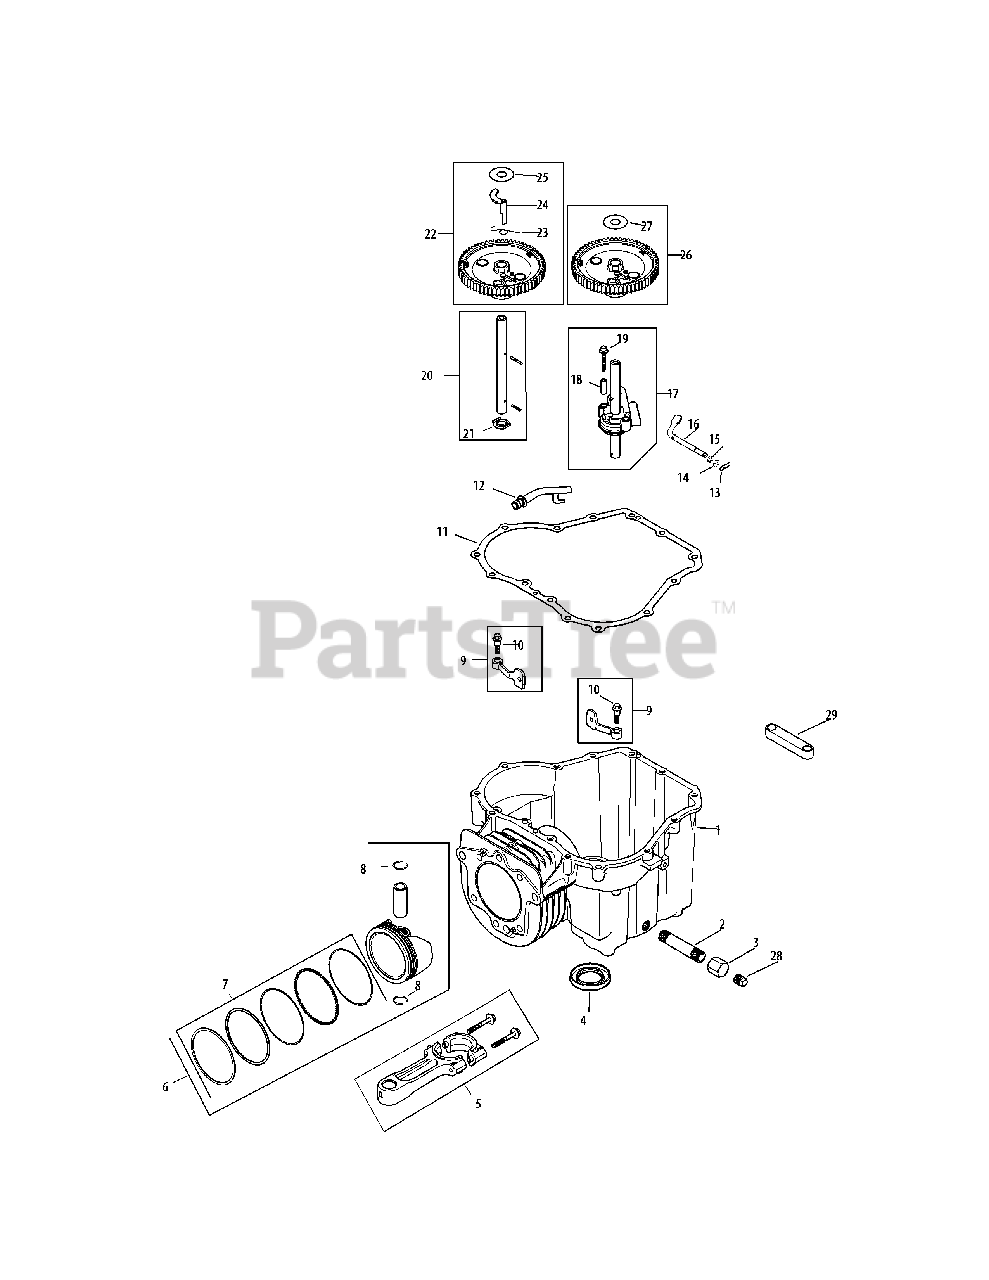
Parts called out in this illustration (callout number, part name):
1	Crankcase
4	Oil Seal
5	Connecting Assembly Rod
6	Piston w/ Ring Set, 94mm (Incl. 7, 8)
7	Ring Set (94mm)
8	Piston Pin Retainer
9	Cam Lever Ass. Kit (Incl. 10)
10	Shd. Thd. Frm. Screw, M6 X 1 X 26
11	Gasket
12	Drainback Tube
13	Hitch Pin Clip
14	Flat Washer, 6 Mm
15	Flat Washer, 1/4
16	Governor Cross Shaft
17	Oil Pump Ass’y Kit (Incl. 11, 18, 19)
18	Oil Pump Screw Spacer
19	Oil Pump Screw
20	Cam Center Shaft Kit (Incl. 21)
21	Thrust Washer
22	Camshaft Ass’y Kit (Incl. 23-25)
24	Acr. Weight
25	Thrust -Acr. Washer
26	Camshaft Ass’y Kit (Incl. 27)
27	Thrust -Acr. Washer
28	Square Head Pipe Plug, 3/8
29	Balance Weight Linkage
